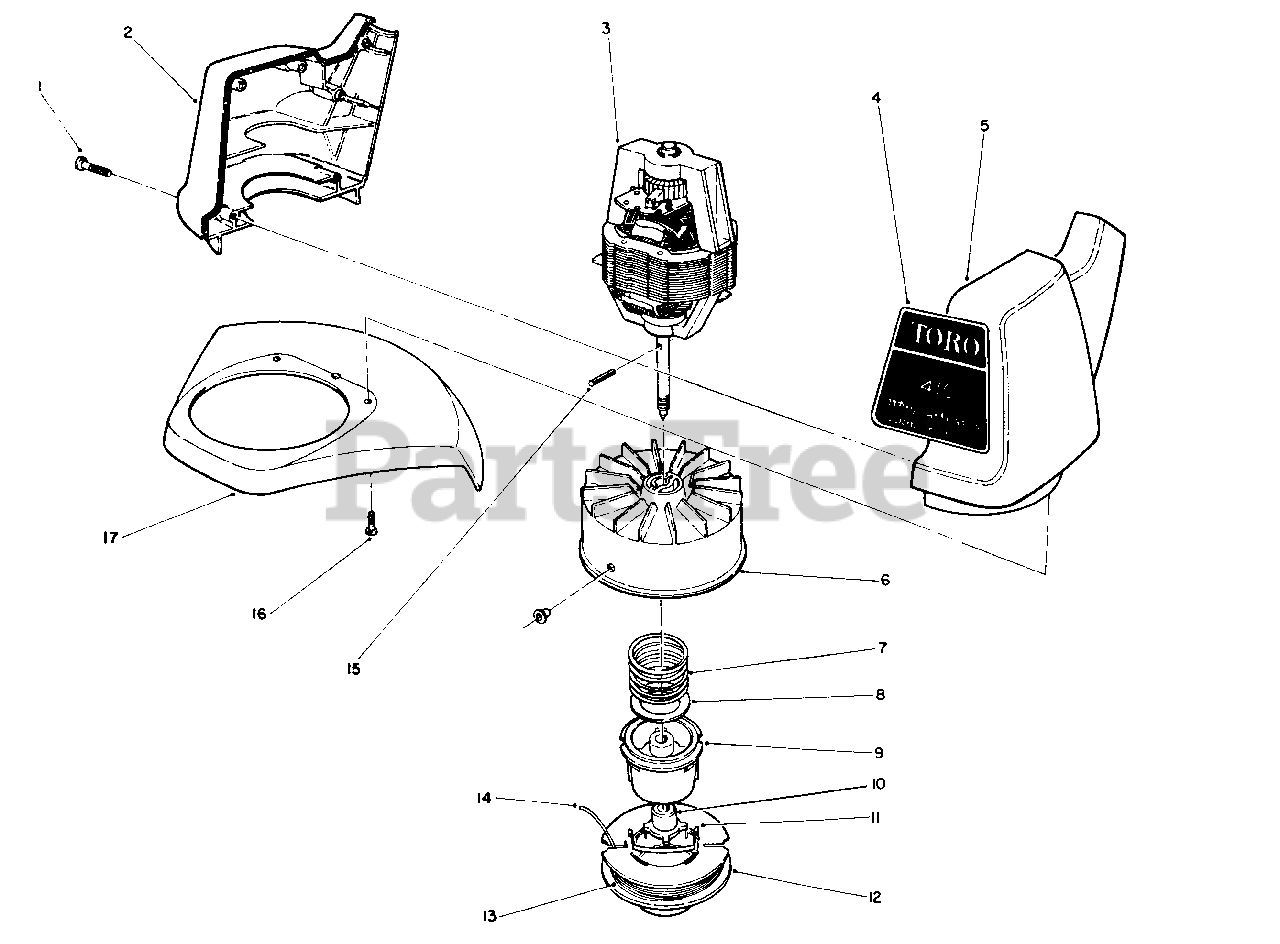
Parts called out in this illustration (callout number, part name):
1	Screw-Thread Forming
2	Housing-Motor (R.H.)
3	Motor-Electric
4	Decal-1410
5	Housing-Motor (L.H.)
6	Drum & Eyelet Assembly
7	Spring-Compression
9	Spool-Core
11	Clip-Saddle
12	Empty Spool
13	50', .065" dia. Cutting Line Prewound on Spool
14	50' Coil-.065" Cutting Line in Coil
15	Pin-Spiral
16	Screw-Thread Forming
17	Shield-Assembly
